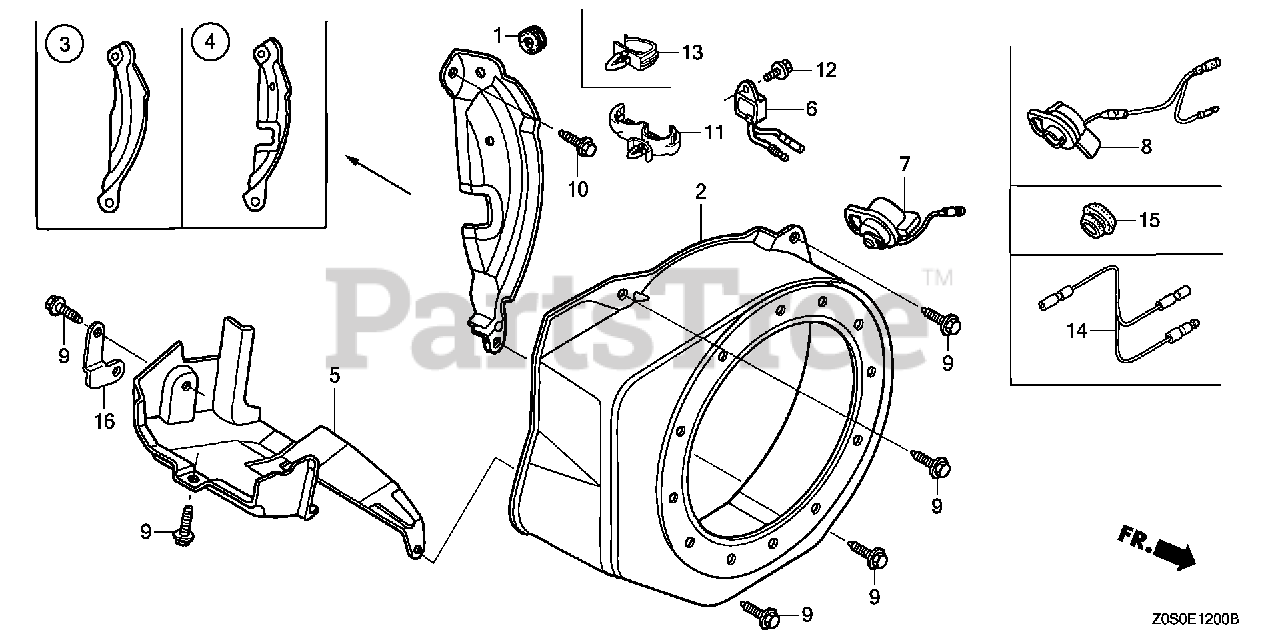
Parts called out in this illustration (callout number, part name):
1	GROMMET, ADJUSTING COVER
2	COVER, FAN *R280* (POWER RED)
3	PLATE, SIDE (OIL ALERT)
6	ALERT UNIT, OIL
8	SWITCH ASSY., ENGINE STOP (TOYO DENSO)
8	SWITCH ASSY., ENGINE STOP
9	BOLT, FLANGE (6X12) (CT200)
10	BOLT, FLANGE (6X20) (CT200)
11	CLIP, HARNESS
12	BOLT, FLANGE (6X8)
